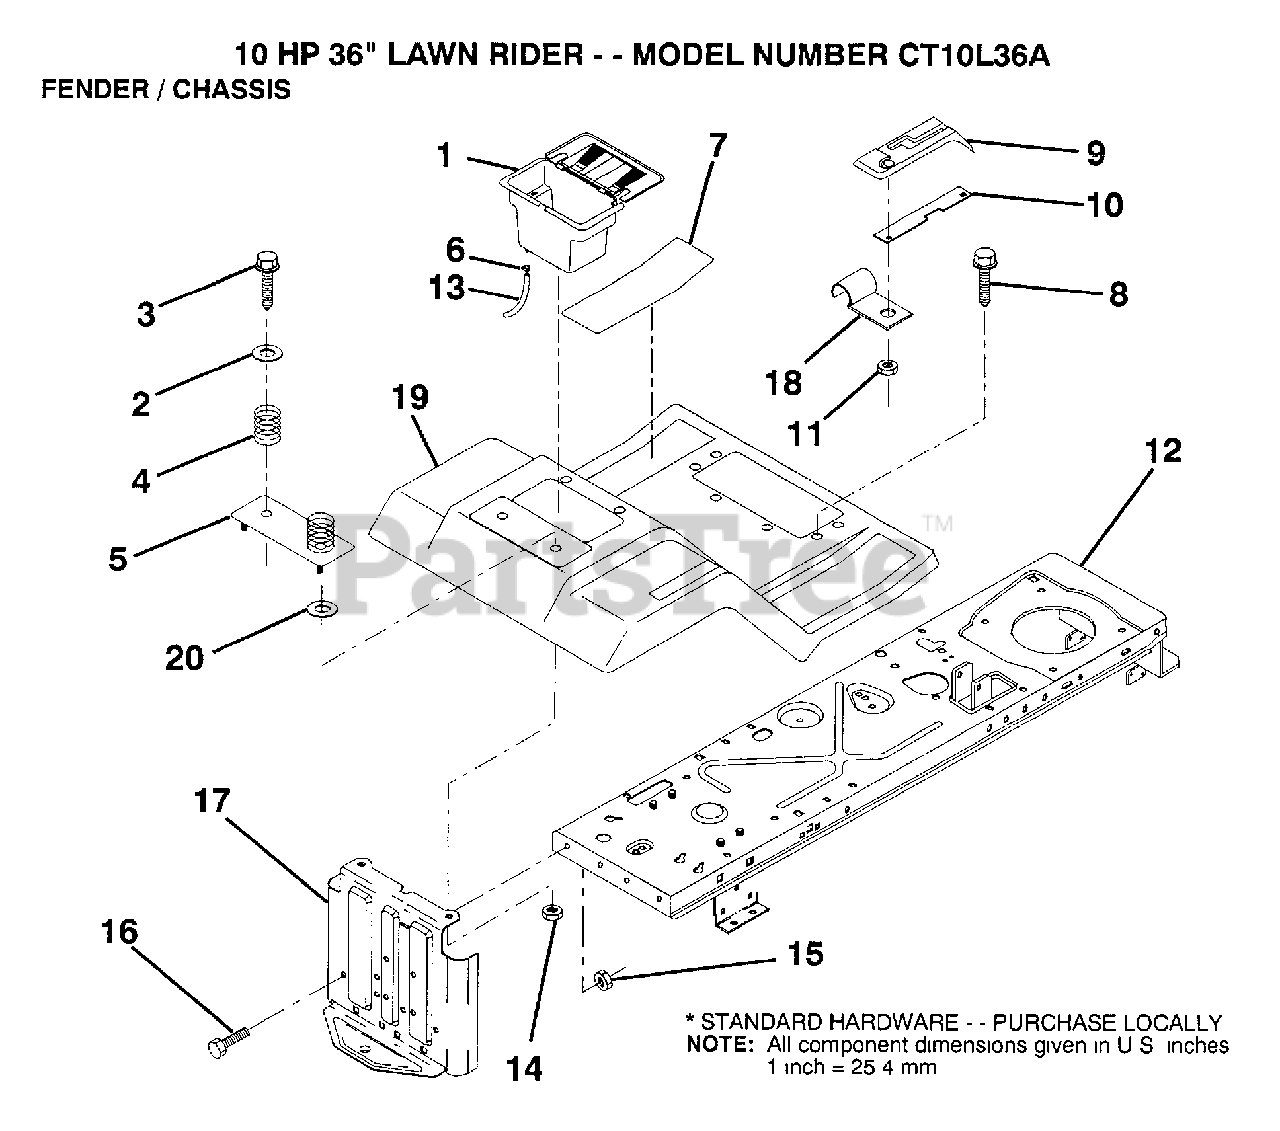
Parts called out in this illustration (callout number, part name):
2	WASHER
3	SCREW
4	SPRING COMPRESSIO
5	BTRY FENDER PLATE
6	HOSE CLAMP T
7	PAD FOOTREST
8	SCREW
9	CONSOLE SHFT 4SP
11	NUT
14	NUT
16	BOLT
17	DRAWBAR
18	"CLIP,INSULATOR"
